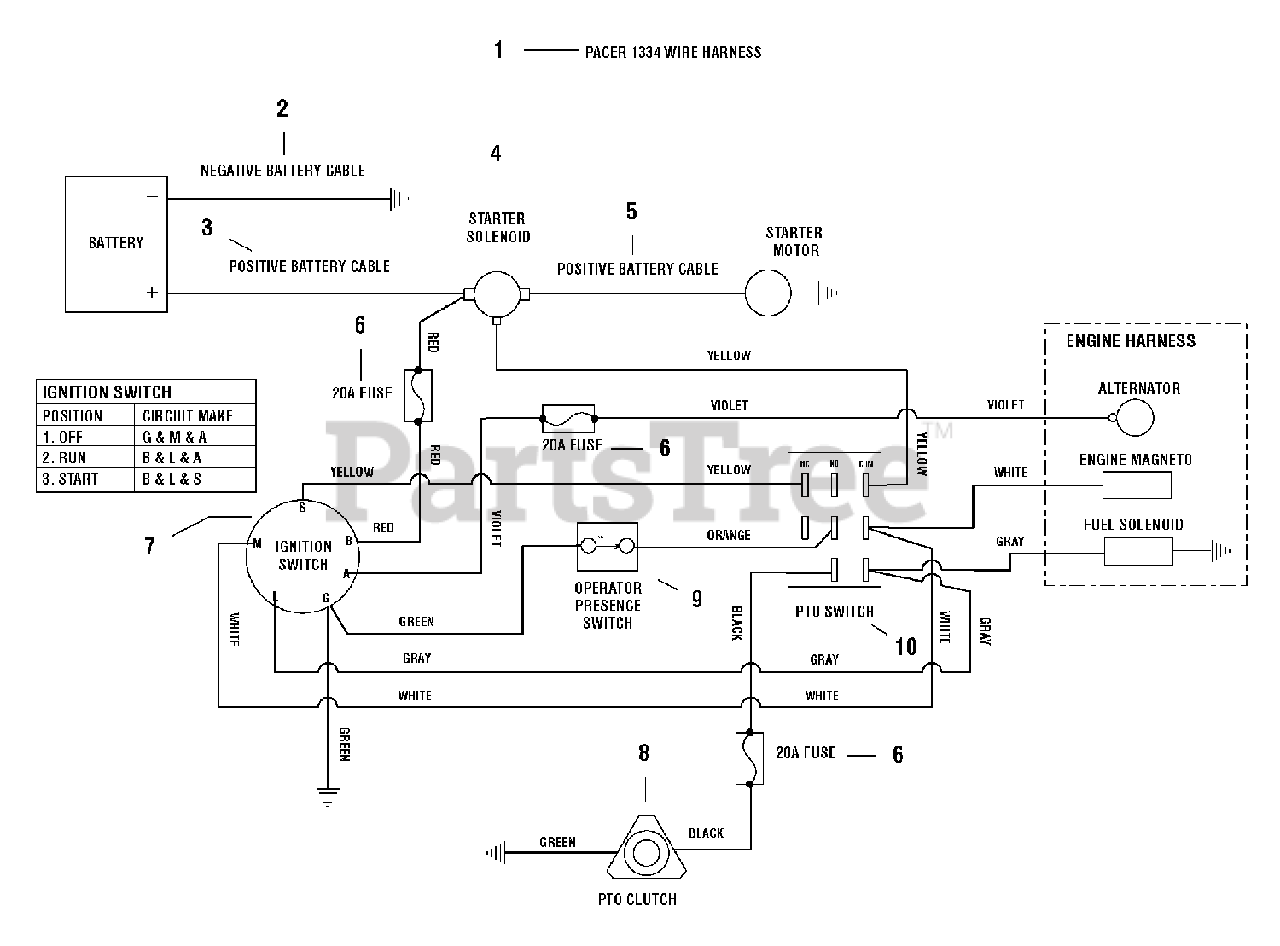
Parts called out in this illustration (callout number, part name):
1	HARNESS, Wire Pacer
2	CABLE, Battery Negative
3	CABLE, Battery Positive
4	SOLENOID, Starter
5	CABLE, Battery Positive
7	SWITCH, Ignition, Complete
8	CLUTCH, PTO
9	SWITCH, Operator Presents
10	SWITCH, PTO
